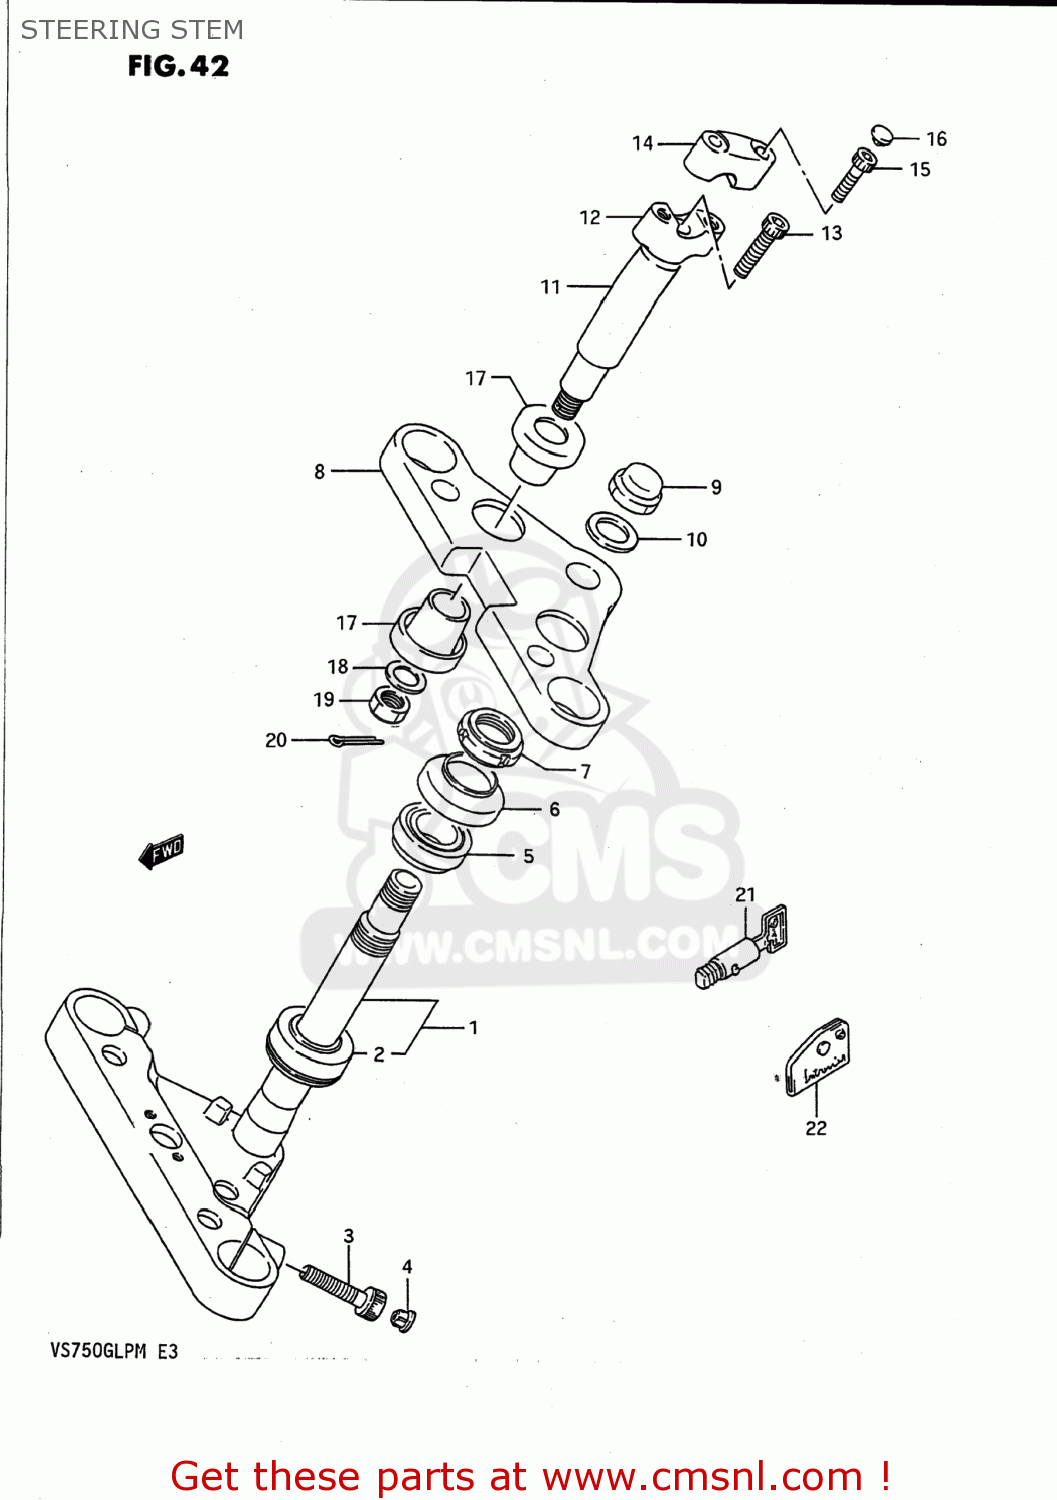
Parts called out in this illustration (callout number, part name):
1	STEM,STEERING
2	BEARING(30X55X17)
3	BOLT,STEERING STEM HEAD
4	CAP(OD:12)
5	TAPER,ROLLER BEARING
6	DUST SEAL,STEERING,UPPER
7	NUT,STEERING STEM(25X44X10)
8	BRACKET,UPR
9	NUT,CAP
10	WASHER
11	STAY,HANDLE
12	HOLDER,HANDLE LWR
13	BOLT
14	HOLDER,HANDLE UPR
15	BOLT, REAR (8X30)
16	CAP(OD:14.5)
17	CUSHION
18	WASHER
19	NUT
20	PIN
21	LOCK SET,STEERING
22	CASE,STEERING KEY
